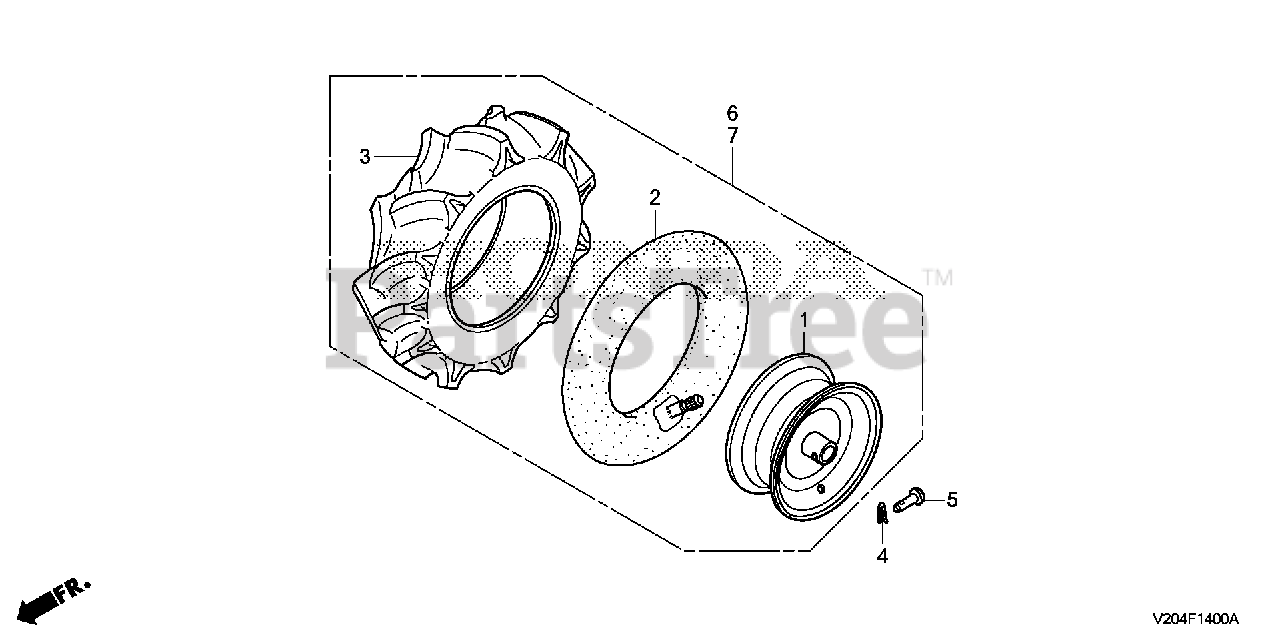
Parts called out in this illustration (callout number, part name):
1	WHEEL (COO)
2	TUBE, TIRE
3	TIRE (4.00-7)
4	PIN, LOCK (8MM)
5	PIN (8X44)
6	WHEEL ASSY., R. (COO)
7	WHEEL ASSY., L. (COO)
